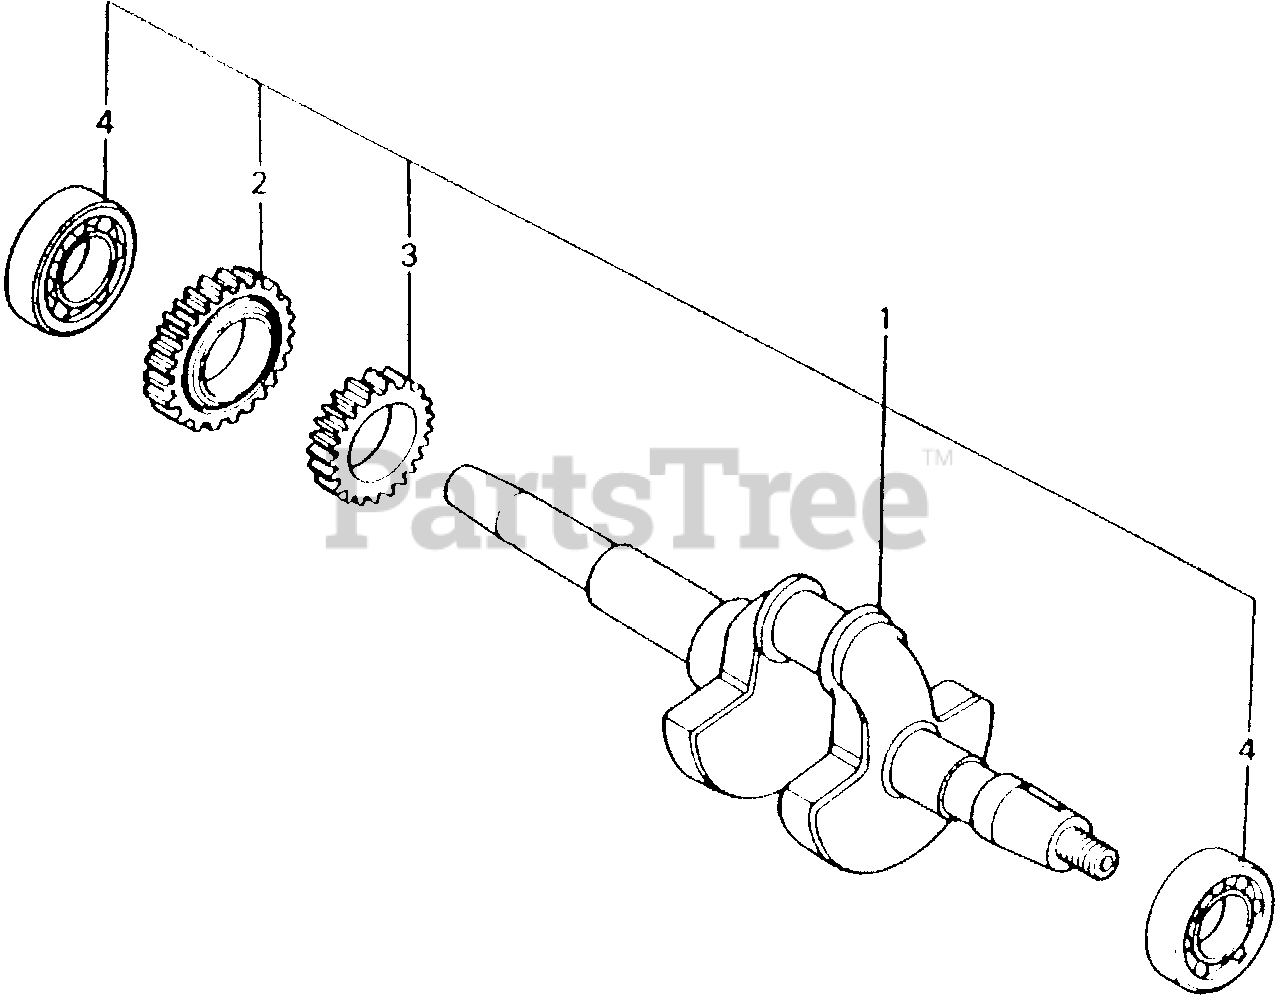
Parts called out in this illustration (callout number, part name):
1	CRANKSHAFT (V-TYPE)
2	GEAR, BALANCER
3	GEAR, TIMING
4	BEARING, RADIAL BALL (6206)
